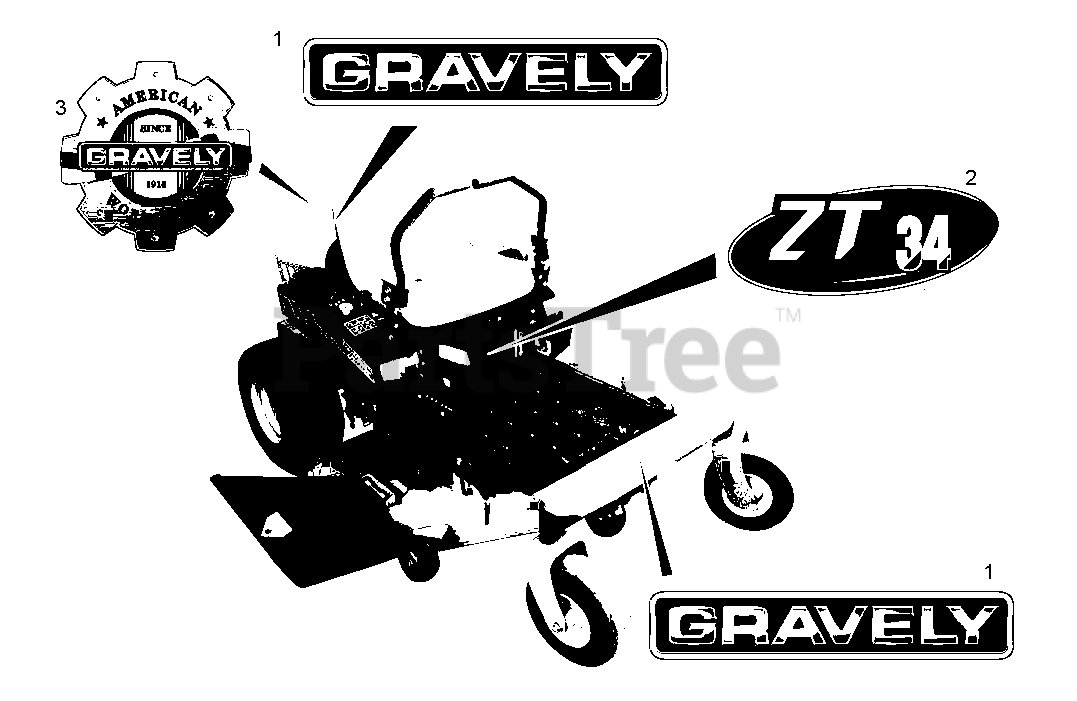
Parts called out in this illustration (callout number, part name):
1	Decal, 9.5" Gravely
2	Decal, ZT 34 (915146, 168)
3	Decal, Gravely Heritage, Large
